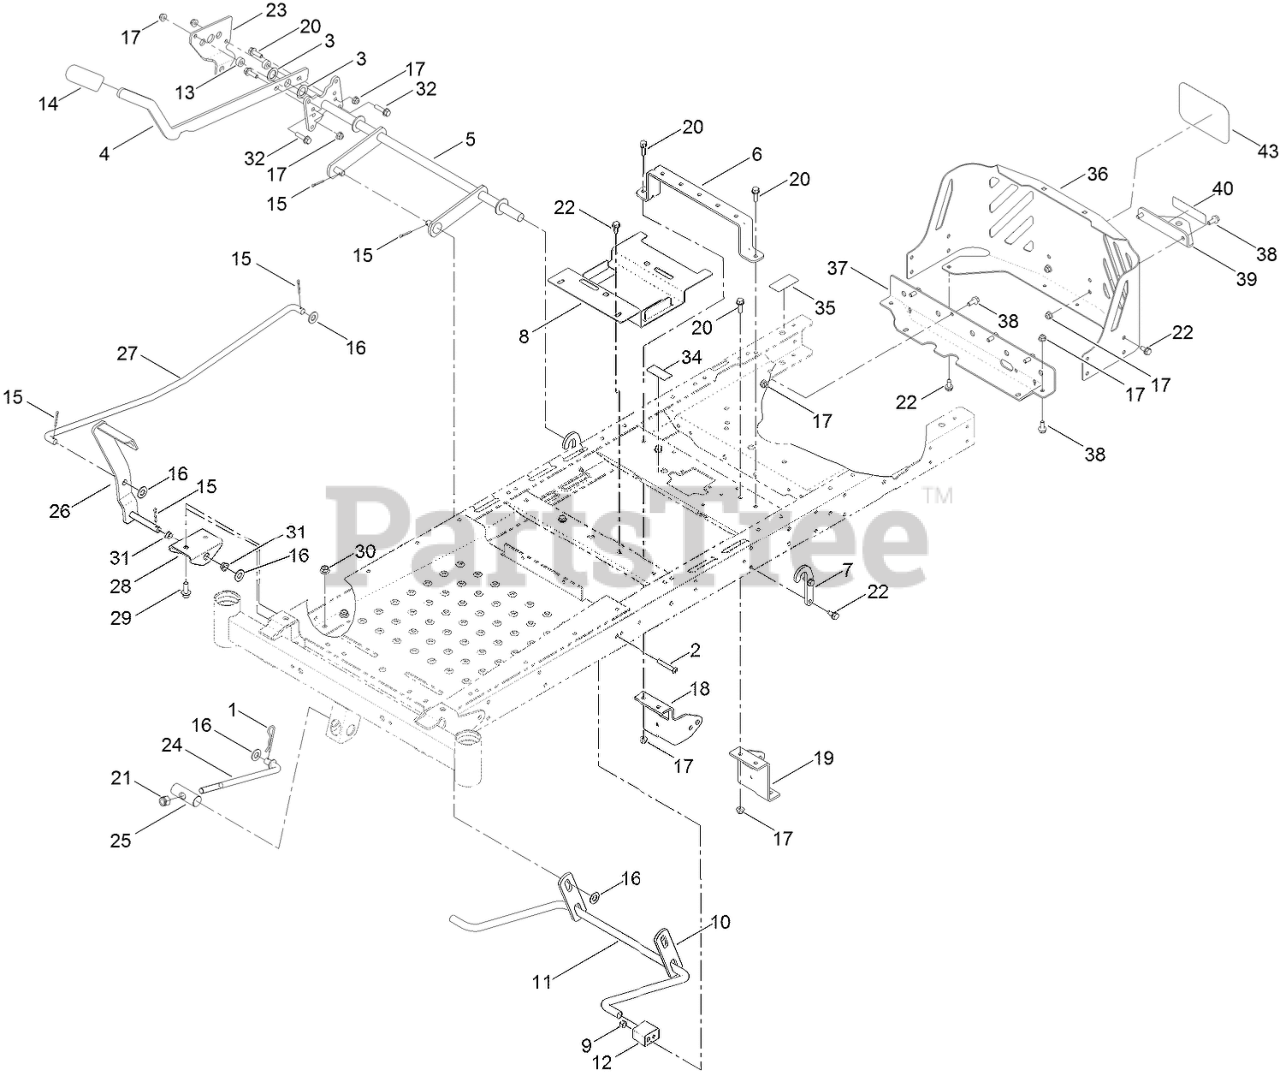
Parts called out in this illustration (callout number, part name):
1	PIN-COTTER
2	SCREW-HSBH
3	WASHER-THRUST
4	LEVER-LIFT
5	LIFT-DECK, NARROW
6	BRACE-SEAT, REAR (NARROW)
7	BRACKET-LIFT
8	BRACKET-BATTERY
9	NUT-LOCK, NI
10	LINK-LIFT
11	ARM-LIFT, REAR
12	BLOCK-PIVOT
13	SPACER
14	GRIP-LEVER
15	PIN-COTTER
16	WASHER-FLAT
17	NUT-HF, NI
18	MOUNT-HYDRO, FRONT (RH)
19	MOUNT-HYDRO, FRONT (LH)
20	SCREW-HHF
21	NUT-HEX
22	SCREW-HWHTF
23	PLATE-FOOTLIFT
24	ROD-MOUNT, DECK
25	PIN-PIVOT
26	PEDAL ASM
27	ROD-FOOTLIFT
28	BRACKET-FOOTLIFT
29	SCREW-HHF
30	NUT-HF, NI
31	BUSHING-FLANGE
32	SCREW-HHF
34	DECAL-LOCATION, SERVICE DEALER
35	DECAL-BYPASS
36	GUARD-ENGINE, NARROW
37	CROSSMEMBER-REAR, NARROW
38	SCREW-HHF
39	BRACKET-HITCH
43	DECAL
